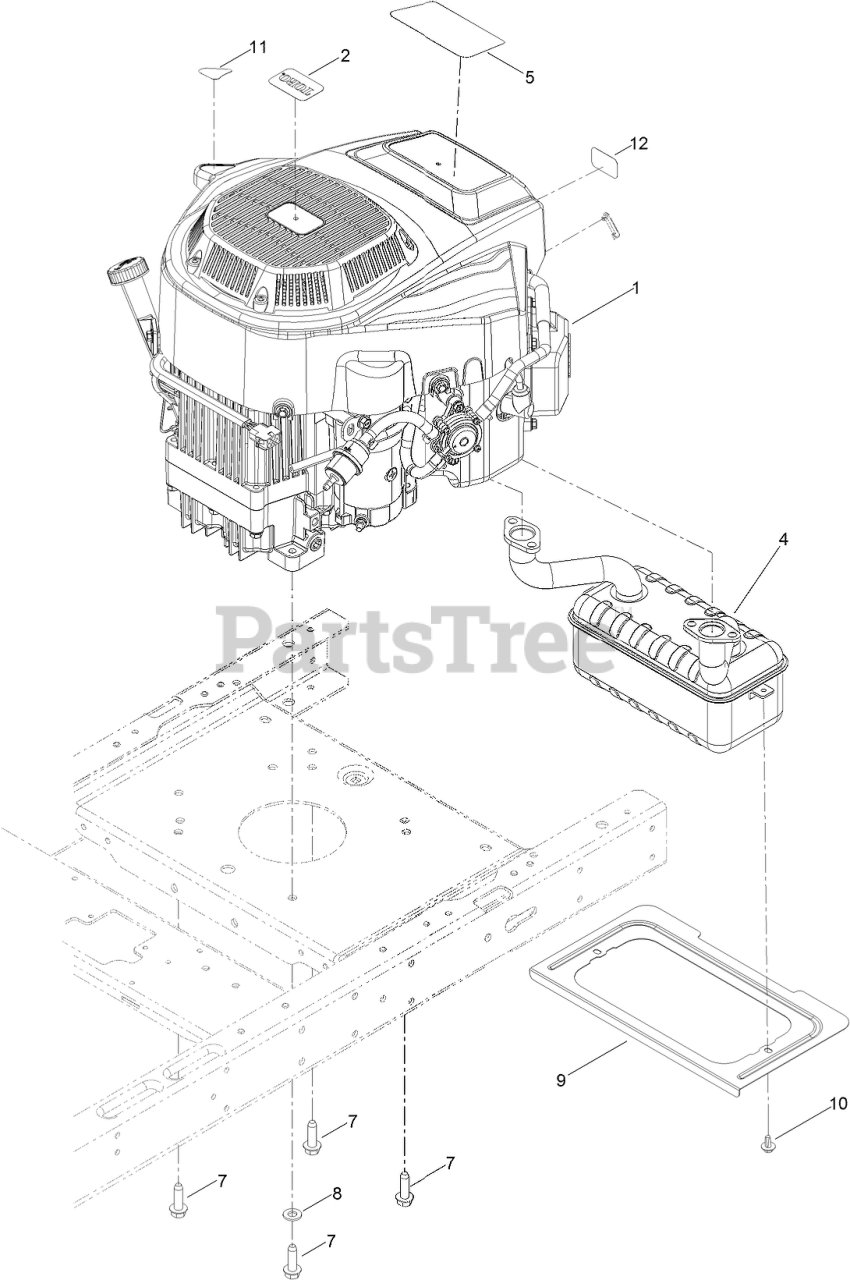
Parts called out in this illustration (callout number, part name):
1	ENGINE-2P77F
4	MUFFLER
5	DECAL-ENGINE
7	SCREW-TAPTITE
8	WASHER-FLAT
9	SHIELD-HEAT
10	SCREW-HHFTF
11	DECAL-DRAIN, OIL
12	PLACARD-INTAKE
